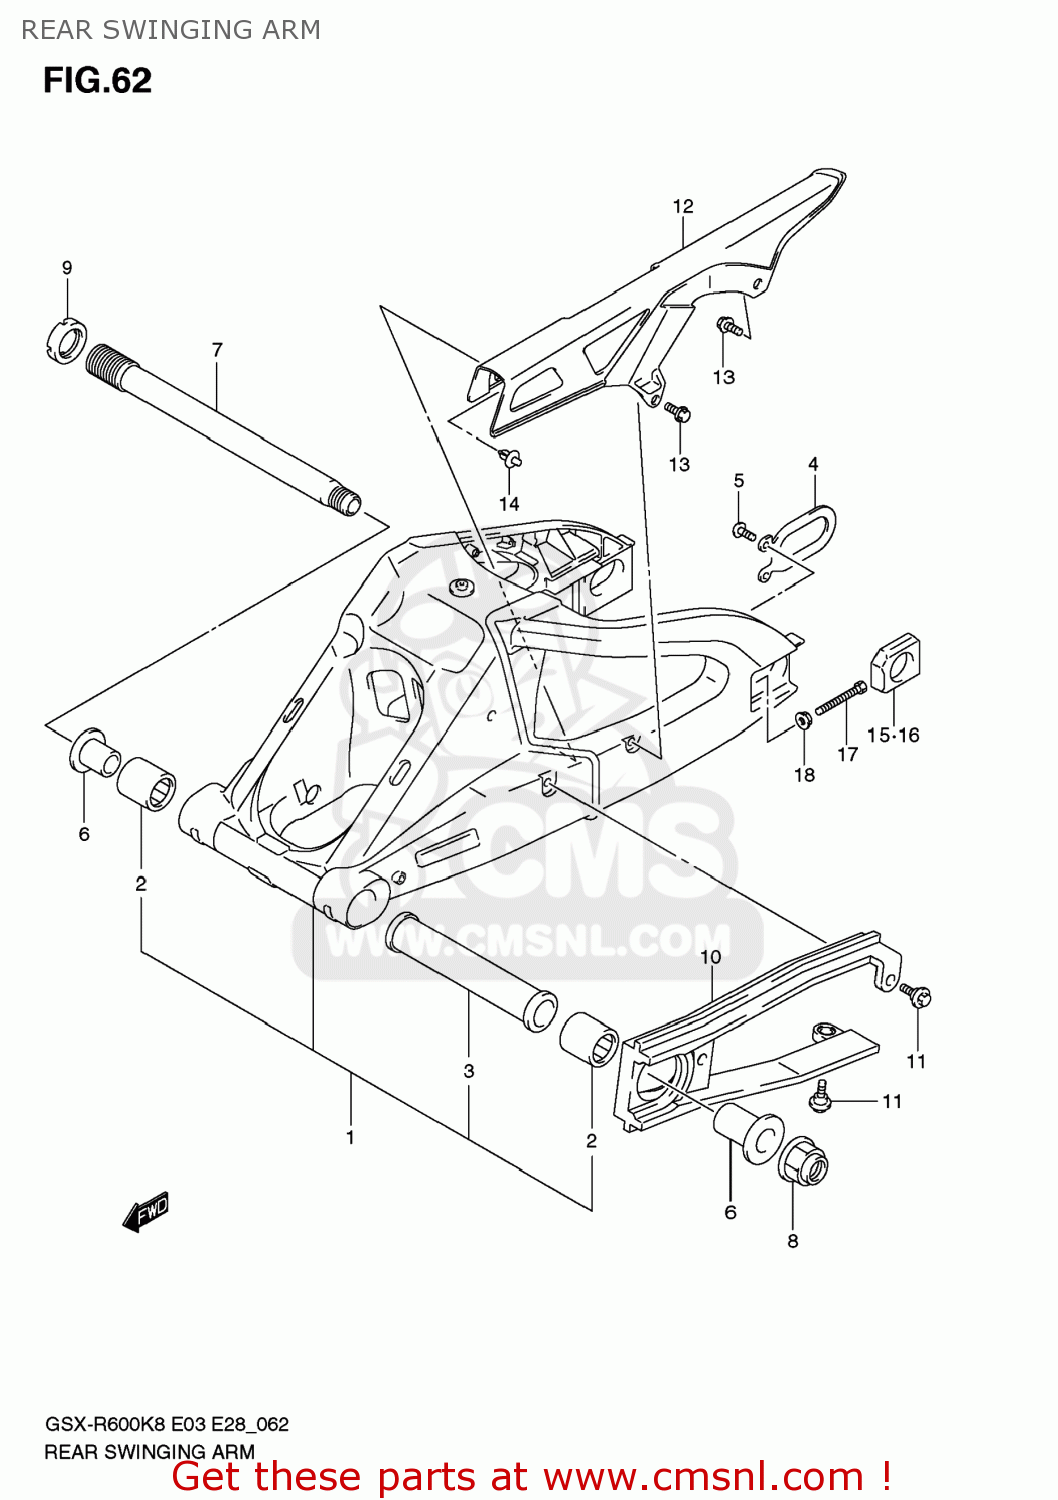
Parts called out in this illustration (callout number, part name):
1	SWINGINGARM ASSY,RR
2	BEARING(27X35X35)
3	SPACER,RR SWG PVT CTR
4	PLATE,RR SWING ARM BRKT
5	SCREW(6X16)
6	SPACER,RR SWGARM PIVOT BEARING
7	SHAFT,RR SWINGINGARM PIVOT
8	NUT
9	NUT,REAR SWGAR
10	BUFFER,CHAIN TOUCH DEFENSE
11	BOLT(6X17.8)
12	CASE,CHAIN
13	BOLT(6X14)
14	CLIP(BLACK)
15	ADJUSTER,CHAIN
16	ADJUSTER,CHAIN
17	BOLT(8X50)
18	NUT
